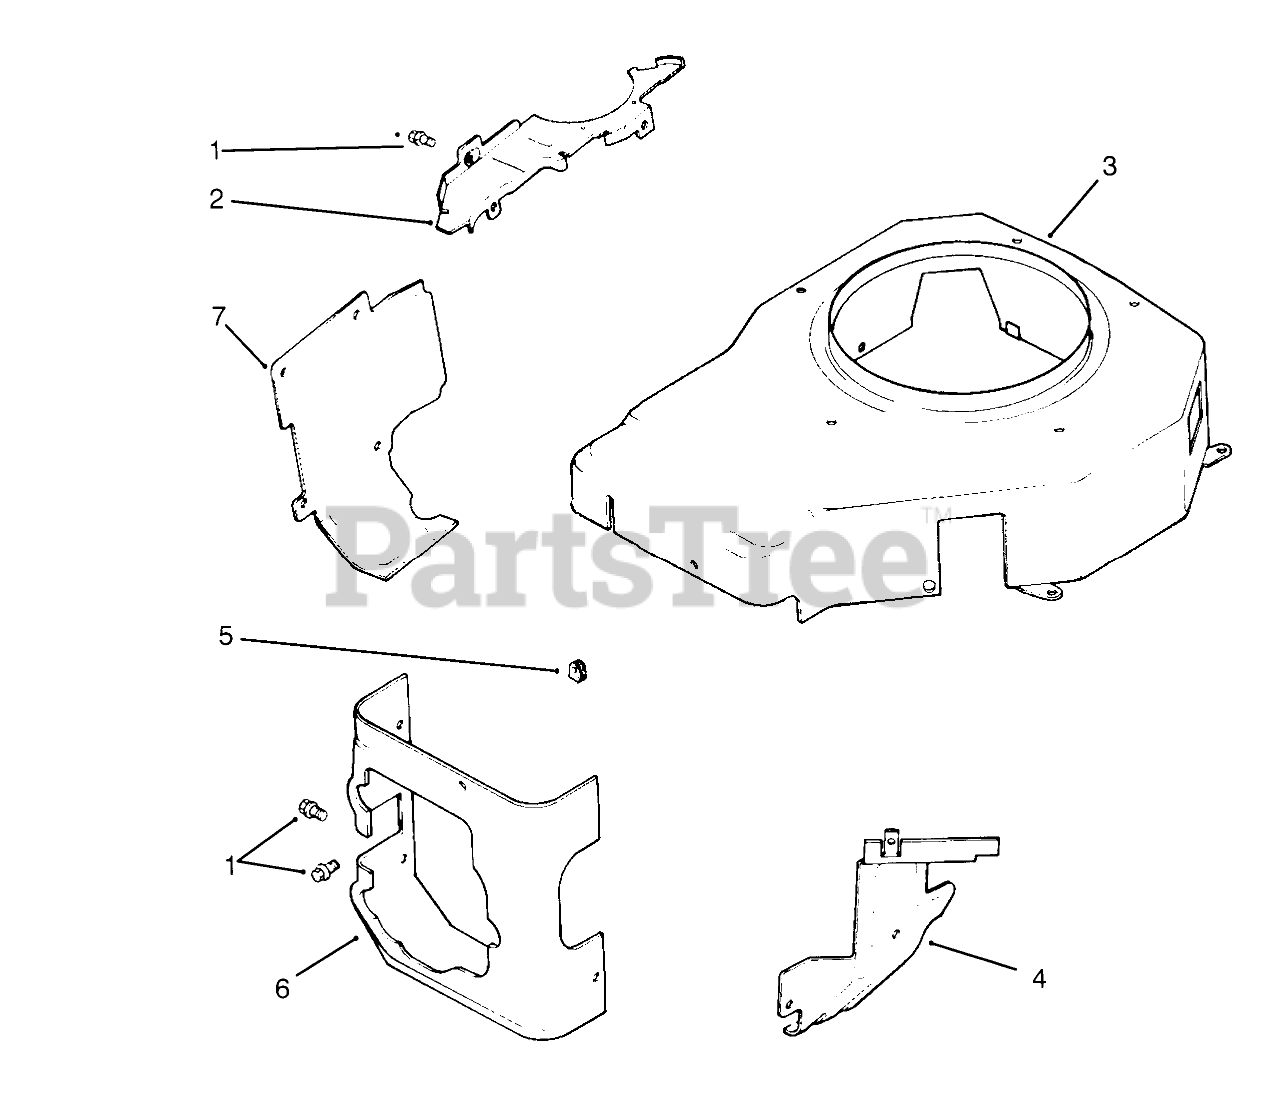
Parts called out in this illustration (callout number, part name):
1	Screw M5x0.8x10 (Only On: 72042,72043,72062,72063)
2	Plate-Blower Housing (Only On: 72042,72043,72062,72063)
3	Housing-Blower (Only On: 72042,72043,72062,72063)
4	Baffle-Carburetor (Only On: 72042,72043,72062,72063)
5	Grommet-Blower Housing (Only On: 72042,72043,72062,72063)
6	Baffle-Cylinder Head (Only On: 72042,72043,72062,72063)
7	Baffle-Cylinder Barrel (Only On: 72042,72043,72062,72063)
